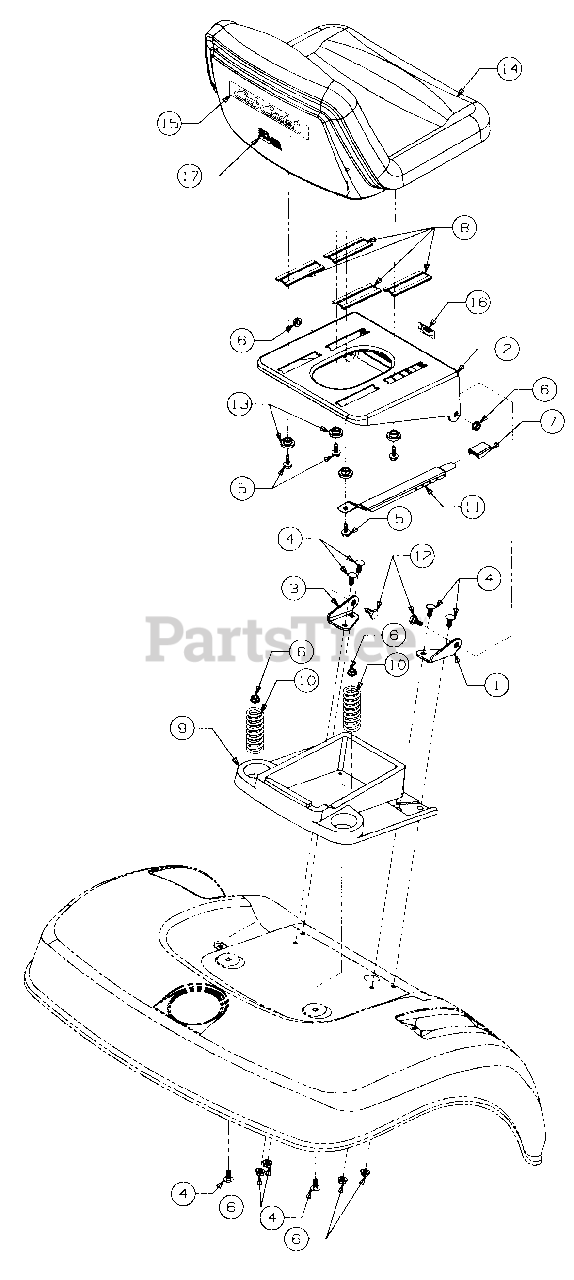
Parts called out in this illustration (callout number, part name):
5	Screw, Hex Wash Sf-Tapp 5/16-18 x.75 Lg
6	Nut, Hex Flange Top Lock, 5/16-18
7	Knob, Seat Adjuster
8	Slide, Seat
9	Tray, Tool
10	Spring, Compression, 1.9 OD x 2.4 Lg
11	Adjuster, Seat
12	Bolt, Shoulder
13	Spacer, Shoulder
14	Seat, High Back
15	Graphic, Seat Back Script
16	Graphic, Seat Adjuster
17	Graphic, Made in USA
